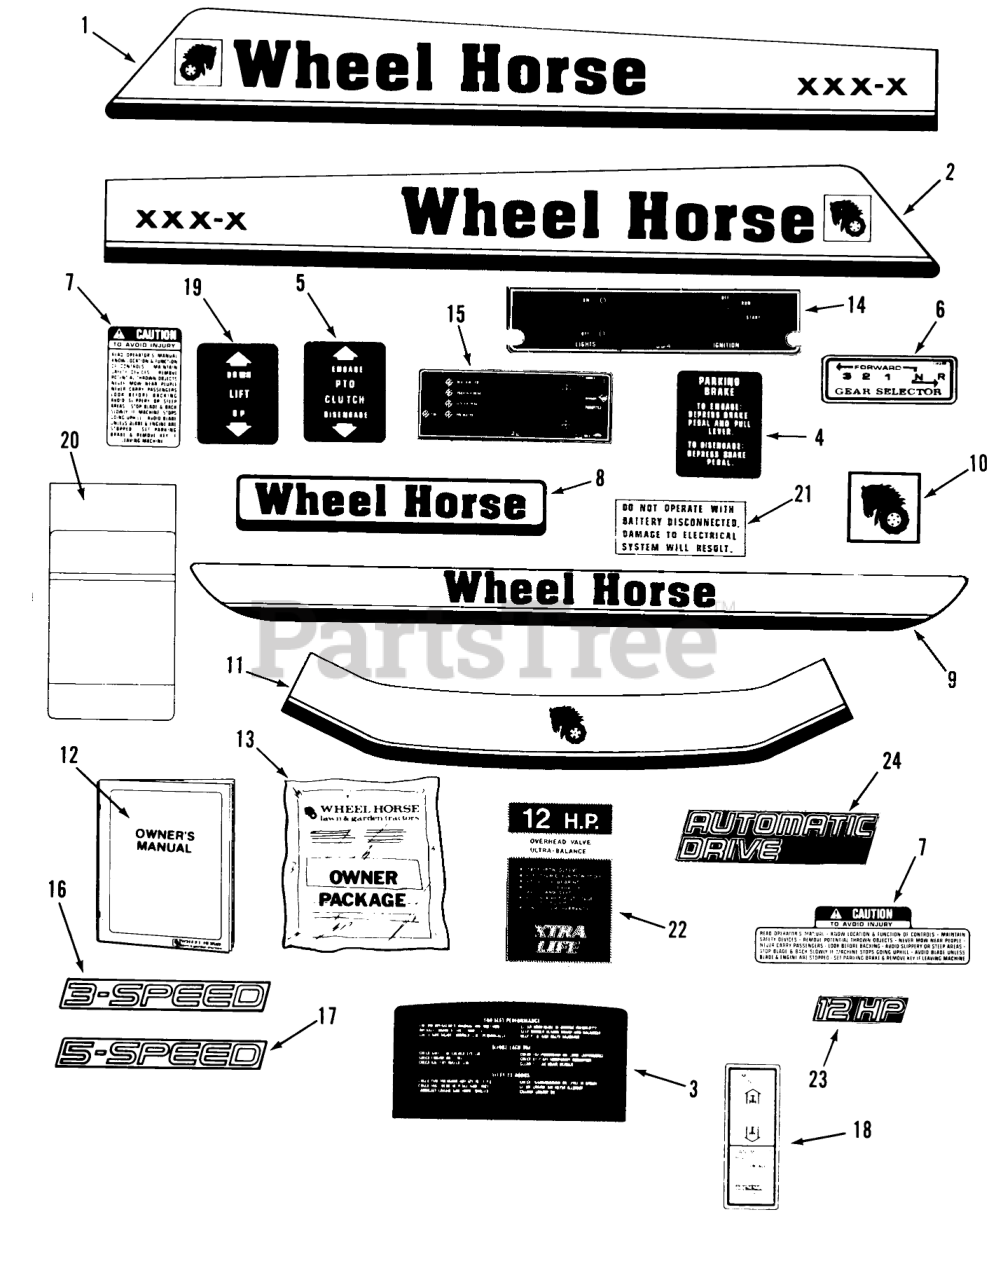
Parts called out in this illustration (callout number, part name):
1	DECAL HOOD RH
2	DECAL HOOD LH
3	DECAL REAR HOOD
4	DECAL-PARKING-BRAKE
5	DECAL PTO
6	Decal-Shift 208-3, 211-3 Only
7	DECAL CAUTION
8	DECAL REAR FENDER
9	Decal-Rear Fender
10	DECAL HOOD FRONT
11	Decal-Hood Front
12	Owners Manual-Tractor
13	New Tractor Loose Parts Package 208-3 Only
14	DECAL BACK PLATE
15	Decal-Dash 252-H
16	DECAL 3SPD
17	DECAL 5SPD
18	Decal-Speed Control-YT12A Only
19	DECAL LIFT
20	Decal-Maintenance
21	DECAL ELECT SYSTEM
22	Decal-Engine-YT12A Only
23	DECAL 12HP
24	Decal-Automatic Drive-YT12A Only
